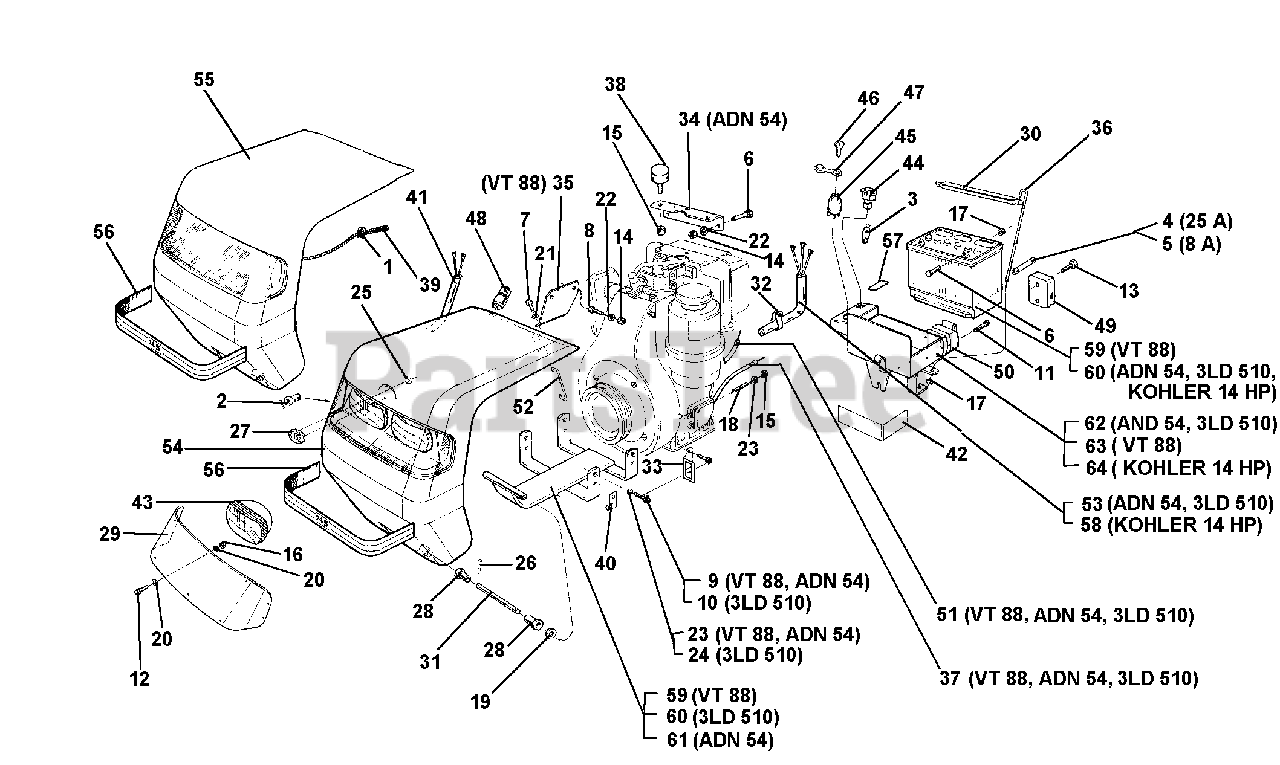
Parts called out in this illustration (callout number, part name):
1	CLAMP, CABLE 3/16
4	FUSE 6 X 25 25A
5	FUSE 6 X 25
6	SCREW TE M6 X 14
7	SCREW M6 X 25
8	SCREW TE M6 X 16
9	SCREW M8 X 20
10	SCREW TE M10 X 20 UNI 5739-8G
11	SCREW TCCEI M4 X 30
12	SCREW TC M4 X 16
13	SCREW TC M4 X 20
17	NUT, SELF LOCKING M6
18	STUD M8 X 40 X 14 X 14
19	FLAT WASHER 10.5 X 21
21	SUPER WASHER 6 DIN 6796
22	WASHER, LOCK 6.4
23	WASHER, LOCK 8.4
24	WASHER, LOCK 10.5
25	WASHER, LOCK FOR PINS D-4
26	PIN, COTTER A 3 X 20 UNI 1336
29	WHITE TRANSPARENT PROTECTION
30	BATTERY BRACKET
31	PIN, COUPLING
32	CLAMP ENGINE
34	TANK COUPLING
35	REGULATOR SUPPORT
36	BATTERY TIEROD
37	CABLE & SHEATH,ACCEL.LOMBAR
39	COVER CABLE
40	SUPPORT, ACCELERATOR CABLE
41	WIRES LIGHTING SYSTEM COVER
42	ANTISHOCK BAT
43	FRONT LIGHT
44	WARNING LIGHT COBO 4706953
45	SWITCH EL. ST. COBO 14110100/1
46	KEY FLAT COBO 14109108
47	LOCK COVER OLSA 15651000
48	LIGHT SWITCH COBO 23101000
49	BOX FOR FUSES COBO 24021000
50	7-POLE SOCKET
51	SHEATH CABLE
53	ELECTRIC STARTER WIRING
54	LIGHTING SYSTEM COVER
55	ENGINE COVER
56	AUTOADHESIVE STRIP
58	KOHLER ELECTRIC STARTER CABLES
59	LOWER COUPLING
60	LOWER COUPLING
61	LOWER COUPLING
62	BATTERY BOX
63	BATTERY SUPPORT
64	KOHLER BATTERY SUPPORT
